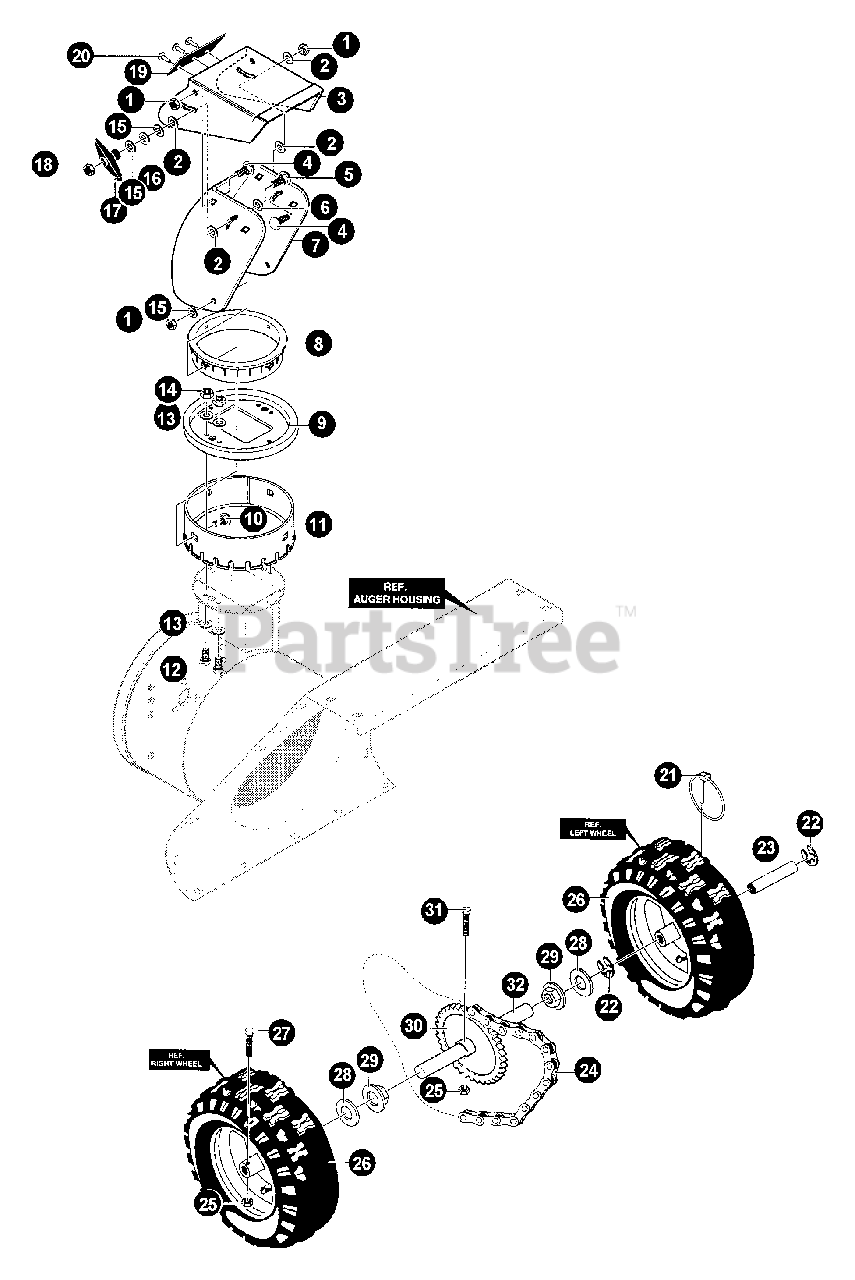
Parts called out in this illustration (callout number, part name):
1	NUT, 5/16 - 18
2	WASHER, PLASTIC
3	CHUTE, UPPER
4	SCREW 5/16"-18
5	BOLT - 5/16-18×1" -- CARRIAGE
6	WASHER, PLASTIC
7	CHUTE, LWR
8	RETAINER, RING INNER
9	COLLAR, CH
10	BOLT, 5/16-18×1.00 CARRLN
11	RETAINER, RING OUTER
12	SCREW 1/4 - 20×75 HHC
13	WASHER
14	NUT, 1/4"-20
15	WASHER
16	WASHER
17	KNOB, T 2 BLADE W/5/16-18 NUT
19	SKIRT, CHUTE EXTENSION
20	RIVET, POP
21	PIN, KLIK
22	RING, RETAINING
23	BUSHING, WHEEL 4" LG
24	CHAIN, ROLLER 420×41
25	NUT, 1/4"-20
26	WHEEL ASSY
27	SCREW - 1/4-20×1.75"
28	WASHER, FLAT
29	BEARING, FL
30	SPROCKET, HUB #40-37TX0.75ID
31	SCREW 1/4"-20×2.25
32	SHAFT, AXLE 6.15
